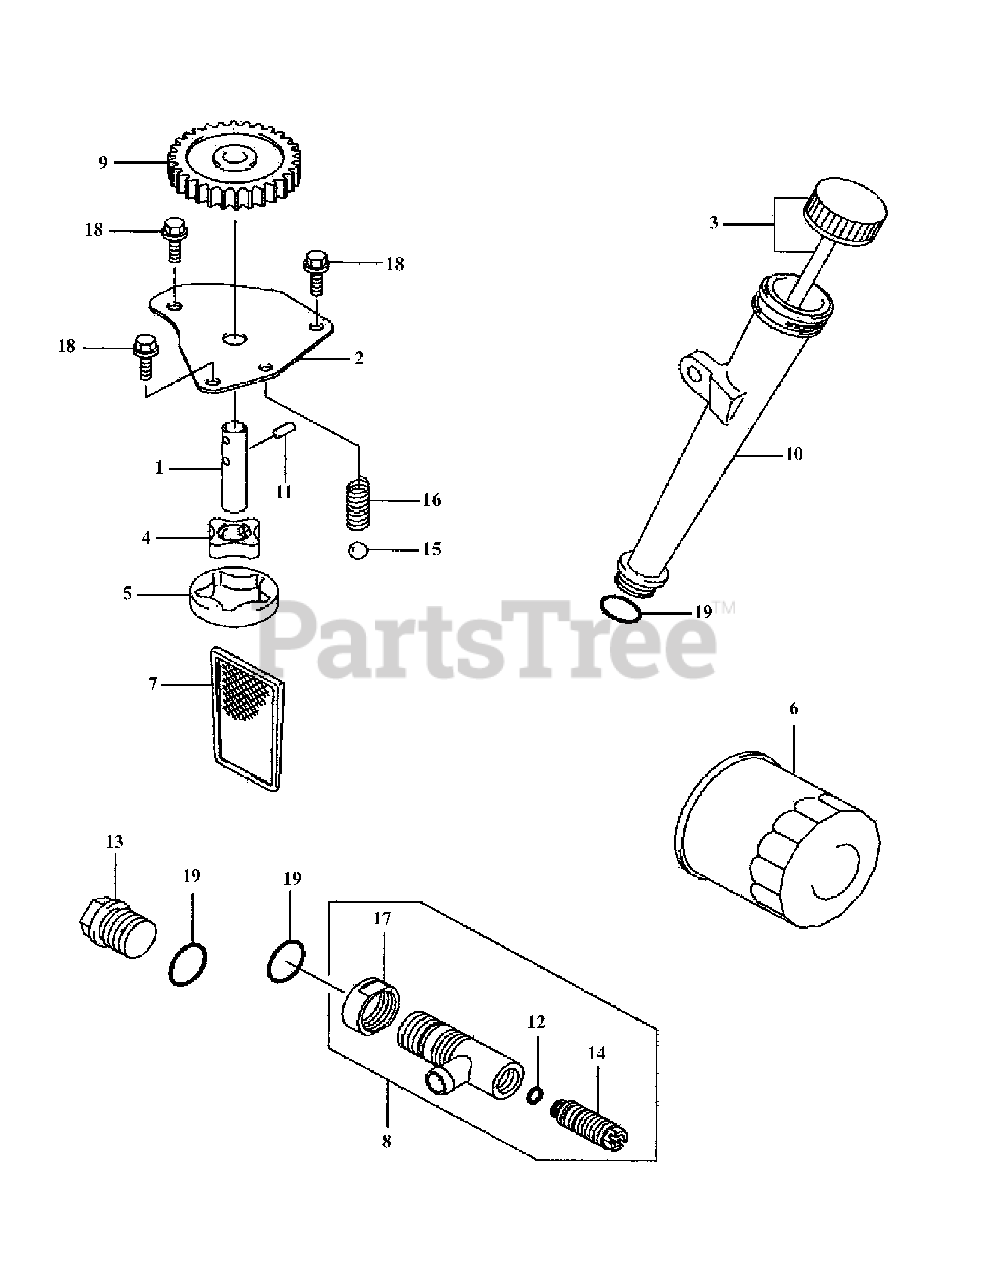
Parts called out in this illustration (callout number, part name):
1	Shaft
3	Cap Assembly
4	Rotor, Pump, In
5	Rotor, Pump, Out
6	Filter, Oil
7	Filter, Oil Screen
8	Valve, Assembly
9	Gear, Spur
11	Pin
13	Plug
14	Plug
18	Bolt, Flanged
